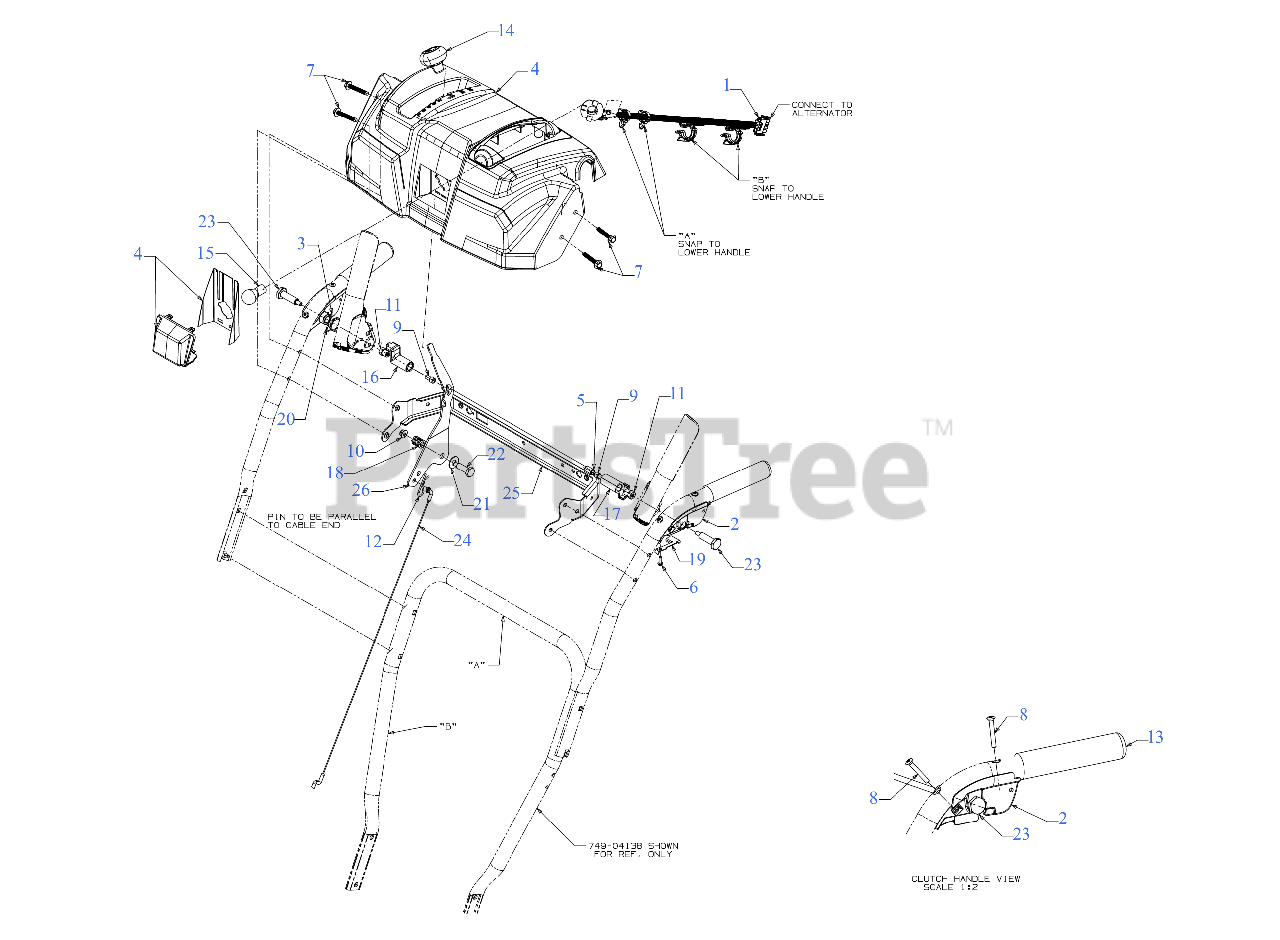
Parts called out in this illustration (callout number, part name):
1	HEADLIGHT SOCKET
1	LIGHT HARNESS
2	CLUTCH LOCK HANDLE ASSEMBLY (LH)
3	CLUTCH LOCK HANDLE ASSEMBLY (RH)
4	HANDLE PANEL ASSEMBLY
6	SCREW #8-16 x .50
7	SCREW 1/4-20 x 1.625
8	SCREW #10-24 x 1.375
9	SCREW 1/4-20 x .50
10	FLANGE LOCK NUT
11	HEX NUT W/PATCH
12	INTERNAL COTTER PIN
14	SHIFT KNOB
15	LAMP-12 VOLT
17	CLUTCH LOCK CAM
18	COMPRESSION SPRING
19	CLUTCH SPRING
20	TORSION SPRING
21	FLAT WASHER .40X.88X.060
22	SHOULDER SCREW
23	SHOULDER SCREW .437 x 1.345 1/4-20
24	SPEED SELECTOR CABLE (PLASTIC)
25	HANDLE SUPPORT BRACKET (POWDER BLACK)
